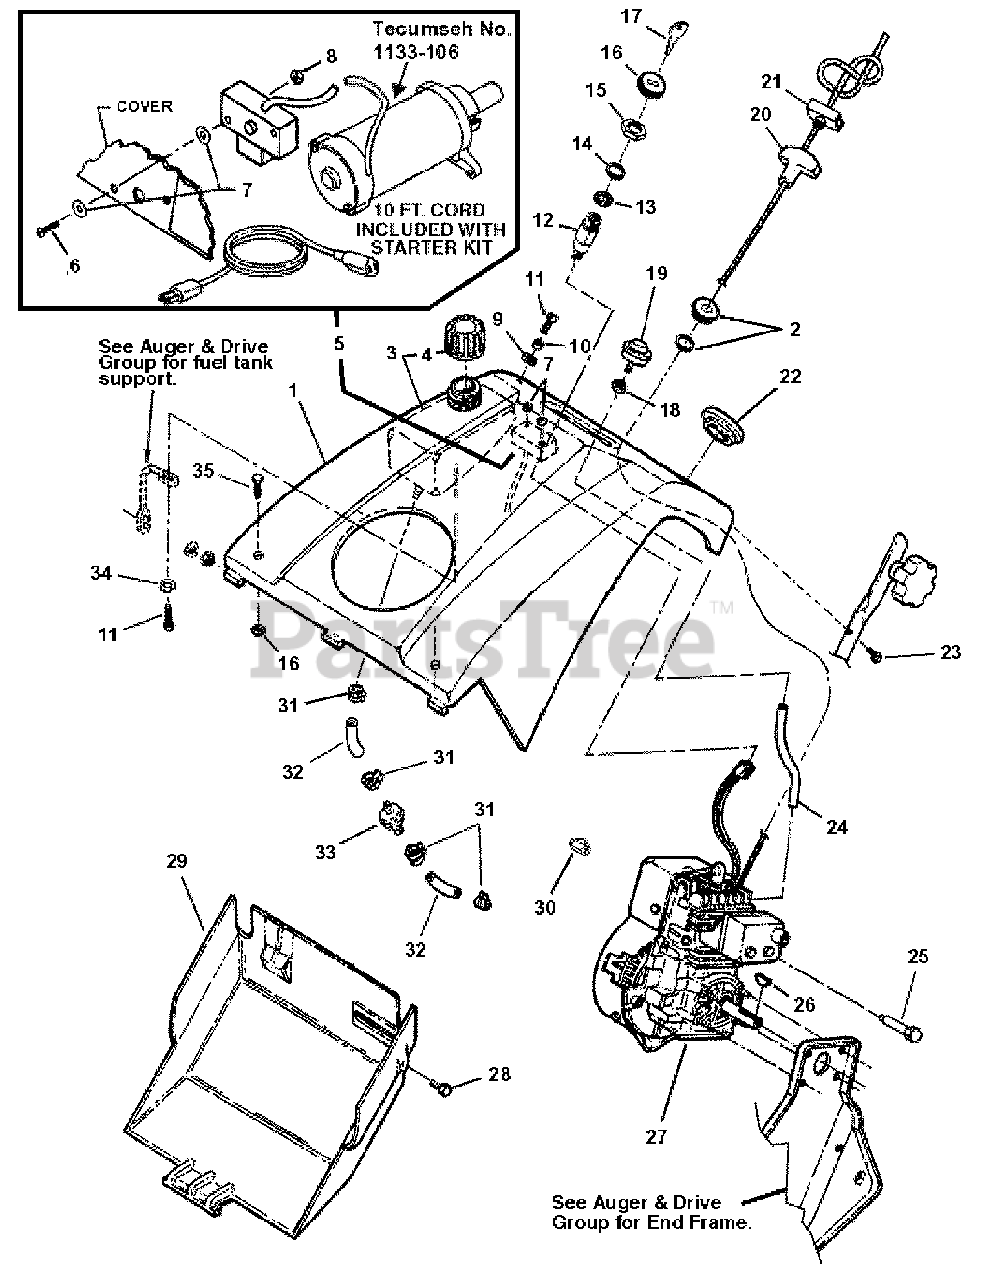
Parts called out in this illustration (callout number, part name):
1	COVER, Top (Includes Ref. No. 2)
2	EYELET, Cover, Pull Rope
3	ASSEMBLY, Fuel Tank (Includes Ref. No. 4)
4	CAP, Fuel Tank
6	SCREW, #10-24 x 1-3/4" Phillips Pan Head, Electric Start Models Only
7	WASHER, #10 Flat, Electric Start Models Only
8	NUT, #10-24 Hex Flange Lock, Electric Start Models Only
9	ISOLATOR, Fuel Tank/Cover
11	SCREW, 1/4-20 x 1/2, Machine
12	SWITCH, Ignition
13	WASHER, 5/8 Internal Tooth Lock
15	NUT, 5/8-32 Hex
18	NUT, 1/4-20 Hex Flange Lock
20	HANDLE, Pull Rope
21	INSERT, Starter Handle
23	SCREW, #8 x 1-1/4" Hi-Lo Taptite
24	HOSE, Primer
25	MUFFLER STUD, LE319
26	KEY, 5/32 x 5/8" Woodruff
27	ENGINE, 3HP Tecumseh, Manual Start, HSK 600-1691T, Engine Crank Shaft - 3.21" Long
27	ENGINE, 3HP Tecumseh, Electric Start, HSK 600-1702T, Engine Crank Shaft - 3.21" Long
28	SCREW, #10-24 x 1/2" Hex Washer Taptite, Torx
29	COVER, Bottom, Manual Start
29	COVER, Bottom, Electric Start
31	CLAMP, Fuel Hose
32	HOSE, Fuel, 1/4 I.D. x 8-1/2" Long
33	FILTER, In-Line
34	WASHER, 1/4 Split Lock
35	CAPSCREW, 1/4-20 x 3/4 Hex Head, G5
